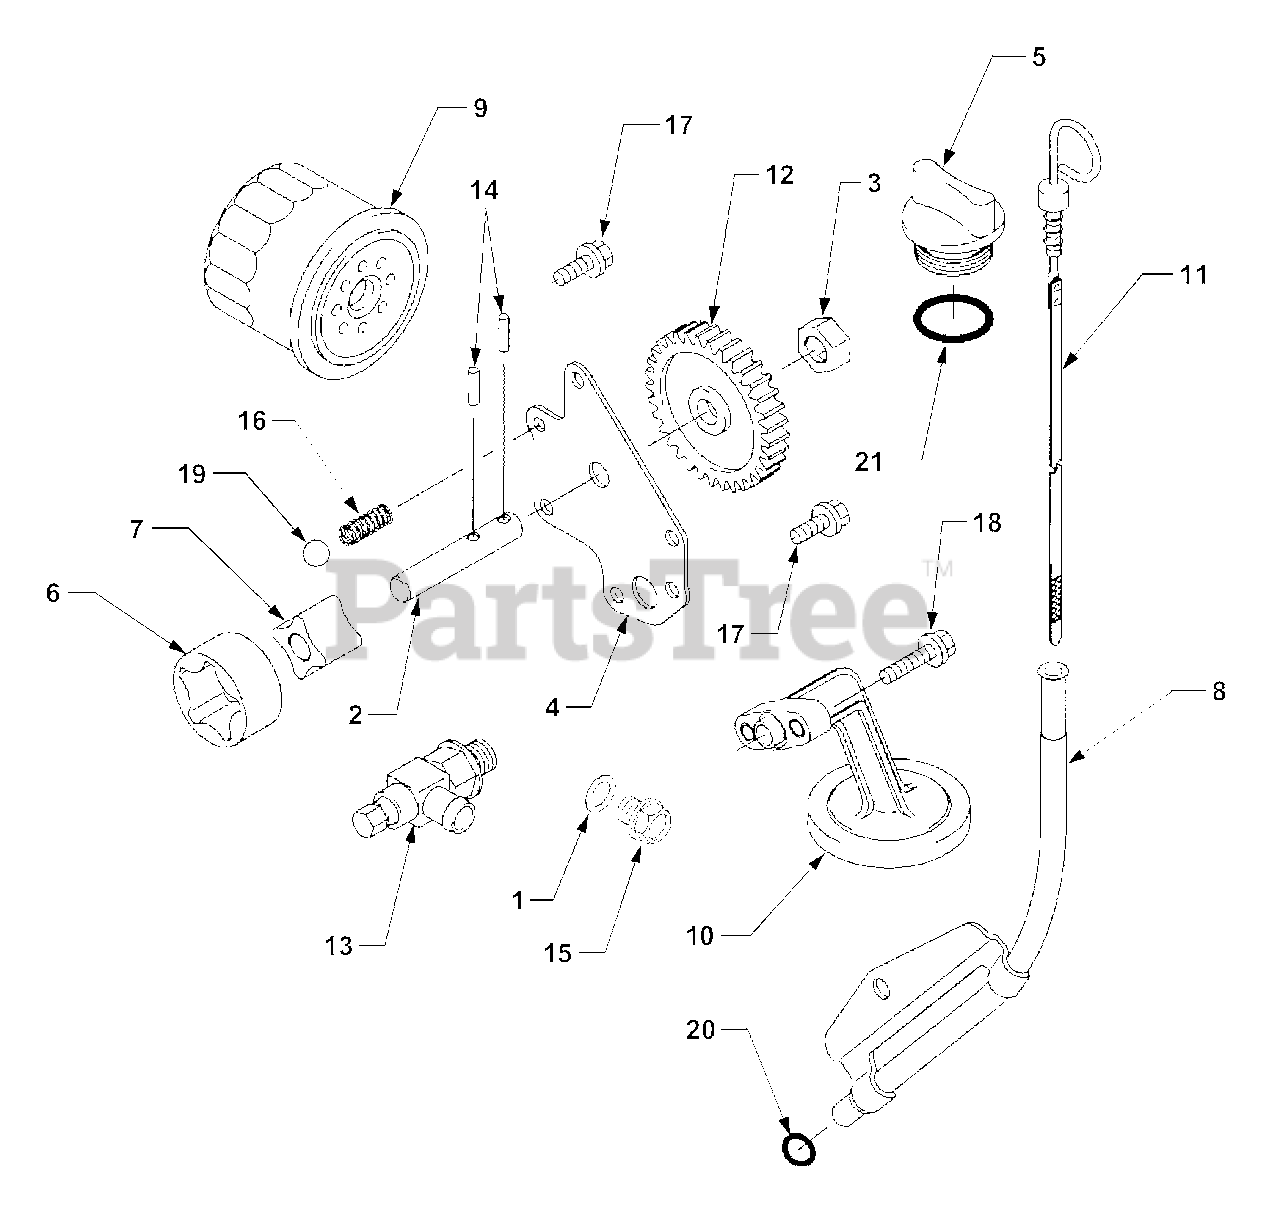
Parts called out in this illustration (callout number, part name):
1	Gasket, Drain Plug
2	Shaft, Oil Pump
3	Holder, Oil Pump
4	Cover, Oil Pump
5	Cap, Oil Filler
6	Rotor, Pump Outer
7	Rotor, Pump Inner
8	Pipe, Oil Gauge
9	Filter, Oil
10	Filter, Oil Suction
12	Gear, Spur, 33T
16	Spring
17	Bolt, Flanged
18	Bolt, Flanged
19	Ball, Steel
